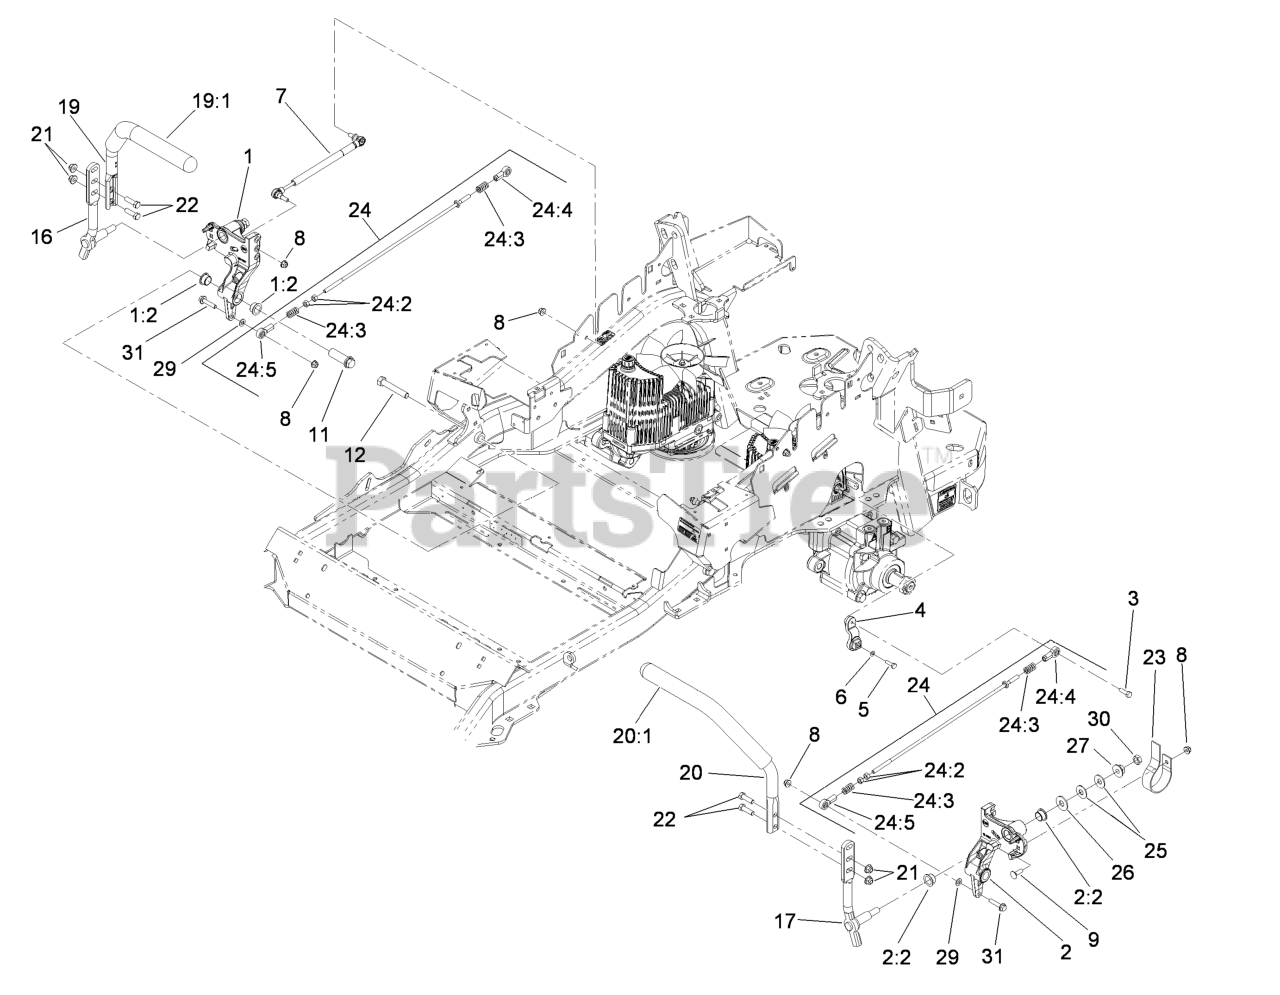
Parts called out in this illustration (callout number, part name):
1	RH MOTION CONTROL AND BUSHING ASM
1:2	BUSHING-FLANGE
2	LH MOTION CONTROL AND BUSHING ASM
2:2	BUSHING-FLANGE
3	SCREW-HH, THREAD LOCKING
4	ARM-CONTROL, PUMP
5	SCREW-HH
6	WASHER-SPRING
7	DAMPER-CONTROL, MOTION
8	NUT-HF, NI
9	BOLT-CARR
11	HUB-THREADED
12	SCREW-HH
16	LEVER-CONTROL MOTION, RH
17	LEVER-CONTROL MOTION, LH
19	RH STEERING HANDLE ASM
19:1	GRIP-LEVER, CONTROL
20	LH STEERING HANDLE ASM
20:1	GRIP-LEVER, CONTROL
21	NUT-HF, NI
22	SCREW-HH
23	SPRING-LEAF
24	PUMP LINKAGE REAR ASM
24:2	NUT-HEX
24:3	SPRING-COMPRESSION
24:4	BALLJOINT-LH
24:5	BALLJOINT-RH
25	WASHER-SPRING
26	WASHER-FLAT
29	WASHER-PLAIN
30	NUT-JAM
31	SCREW-HHF
